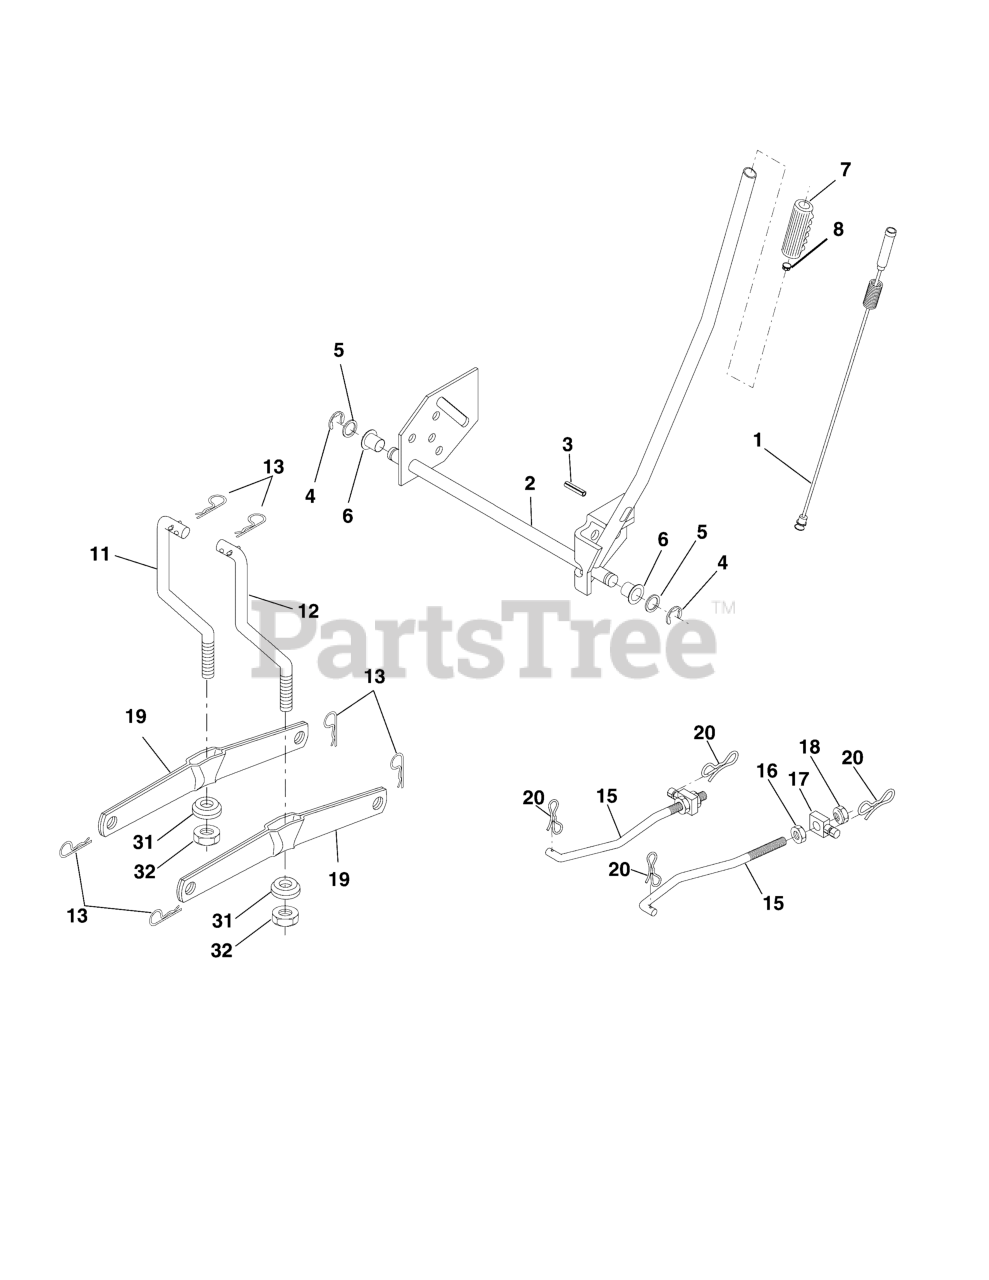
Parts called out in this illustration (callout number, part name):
1	Plunger Asm Lift Lever
2	Shaft Asm Lift RH
3	Pin Groove 1 500 Zinc
4	E Ring #5133-62
5	Washer 21/32 x 1 x 21 Ga.
6	Bearing Nylon Blk 629 Id
7	Grip Handle
8	Button Plunger
11	Link Lift LH Fixed Length
12	Link Lift RH Fixed Length
13	Retainer Spring
15	Link Front
16	Nut Jam Hex 1/2-13 unc
17	Trunnion
18	Nut Lockw/Wsh 1/2-13 unc
19	Arm Suspension Rear
20	Pin Cotter 7/16 Bow Tie Lock
31	Bearing Pvt Lift
32	Nut Crownlock 3/8-24
